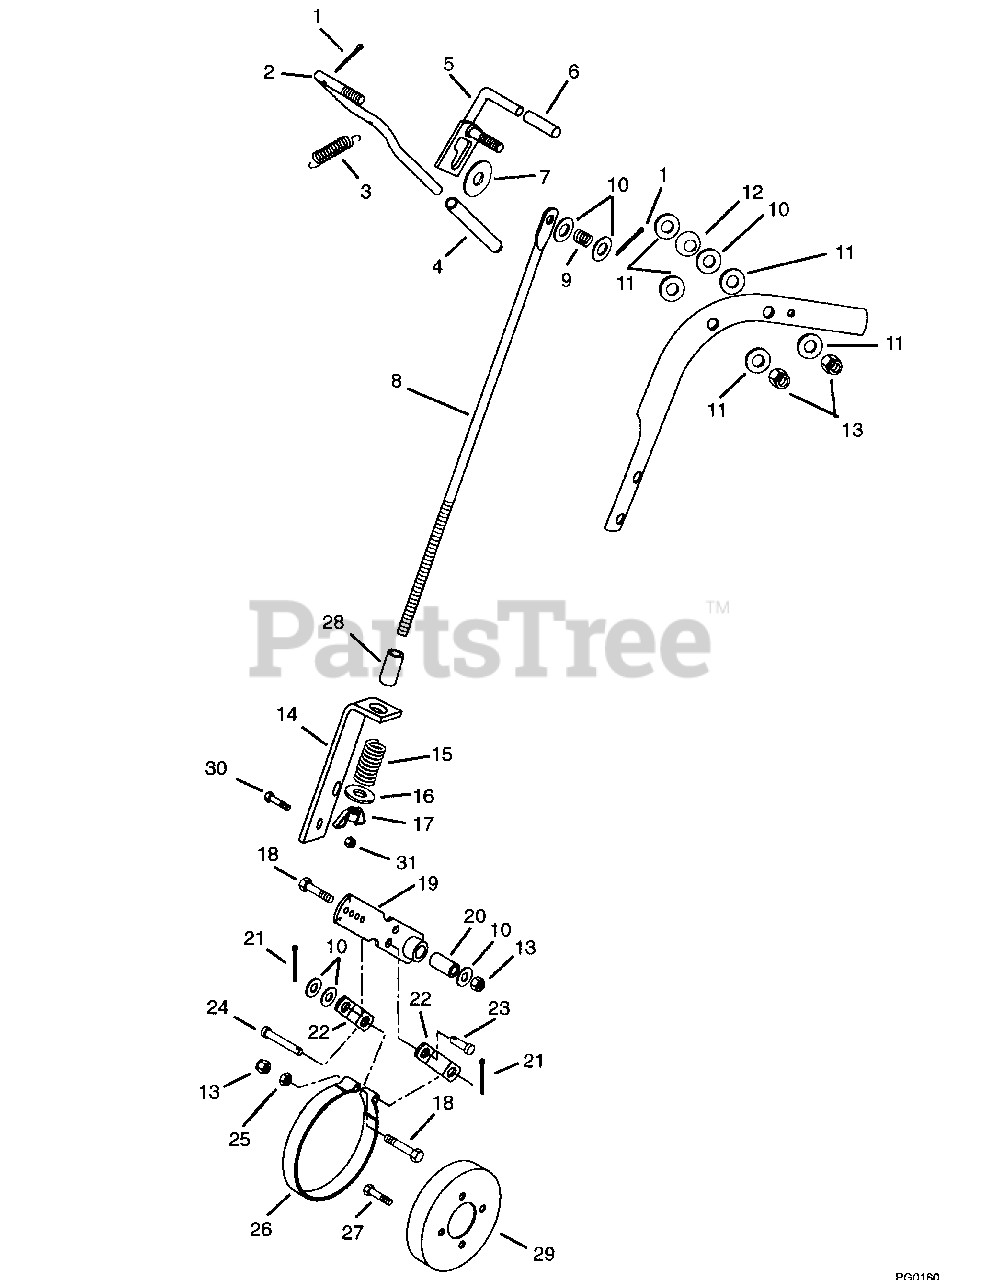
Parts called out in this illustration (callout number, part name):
1	Pin-Cotter .09 x.75
2	Lever, Hand Control
3	Spring-Tension .041 x .500 x 1.750
4	Grip, Hand Clutch Lever
5	Weldment, Neutral Lock Lever
6	Tip-Brake Lock Lever
7	Washer-Flat-Steel .438 x 1.375 x .083
8	Rod, Brake Pull
9	Spring-Compression .045 x .600 x .750
10	Washer-Flat-Steel .406 x .812 x .065
11	Washer-Flat-Nylon .375 x .75 x .125
12	Washer-Spring .375
13	Nut-Locking-Nylon .375-16
14	Bracket, Brake Pull
15	Spring-Compression .072 x .561 x 2.50
16	Washer-Flat-Steel .344 x .688 x .065
17	Nut-Wing .31-18
18	Bolt-Hex .38-16 x 2.00 Grade 5
19	Weldment, Brake Arm PRO-250
20	Bushing, Sleeve .391 x .622 x .950
21	Pin-Cotter .12 x .75
22	Link, Brake Arm
23	Pin-Clevis .38 x .594
24	Pin-Clevis .372 x 1.25
25	Nut-Hex .375-16
26	Assembly, Brake Band
27	Bolt-Hex .31-18 x 1.50 Grade 5
28	Bushing .327 x .411 x 4.00
29	Drum, Brake
30	Bolt-Hex .25-20 x .75 Grade 5
31	Nut-Locking- Nylon .250-20 Grade 2
